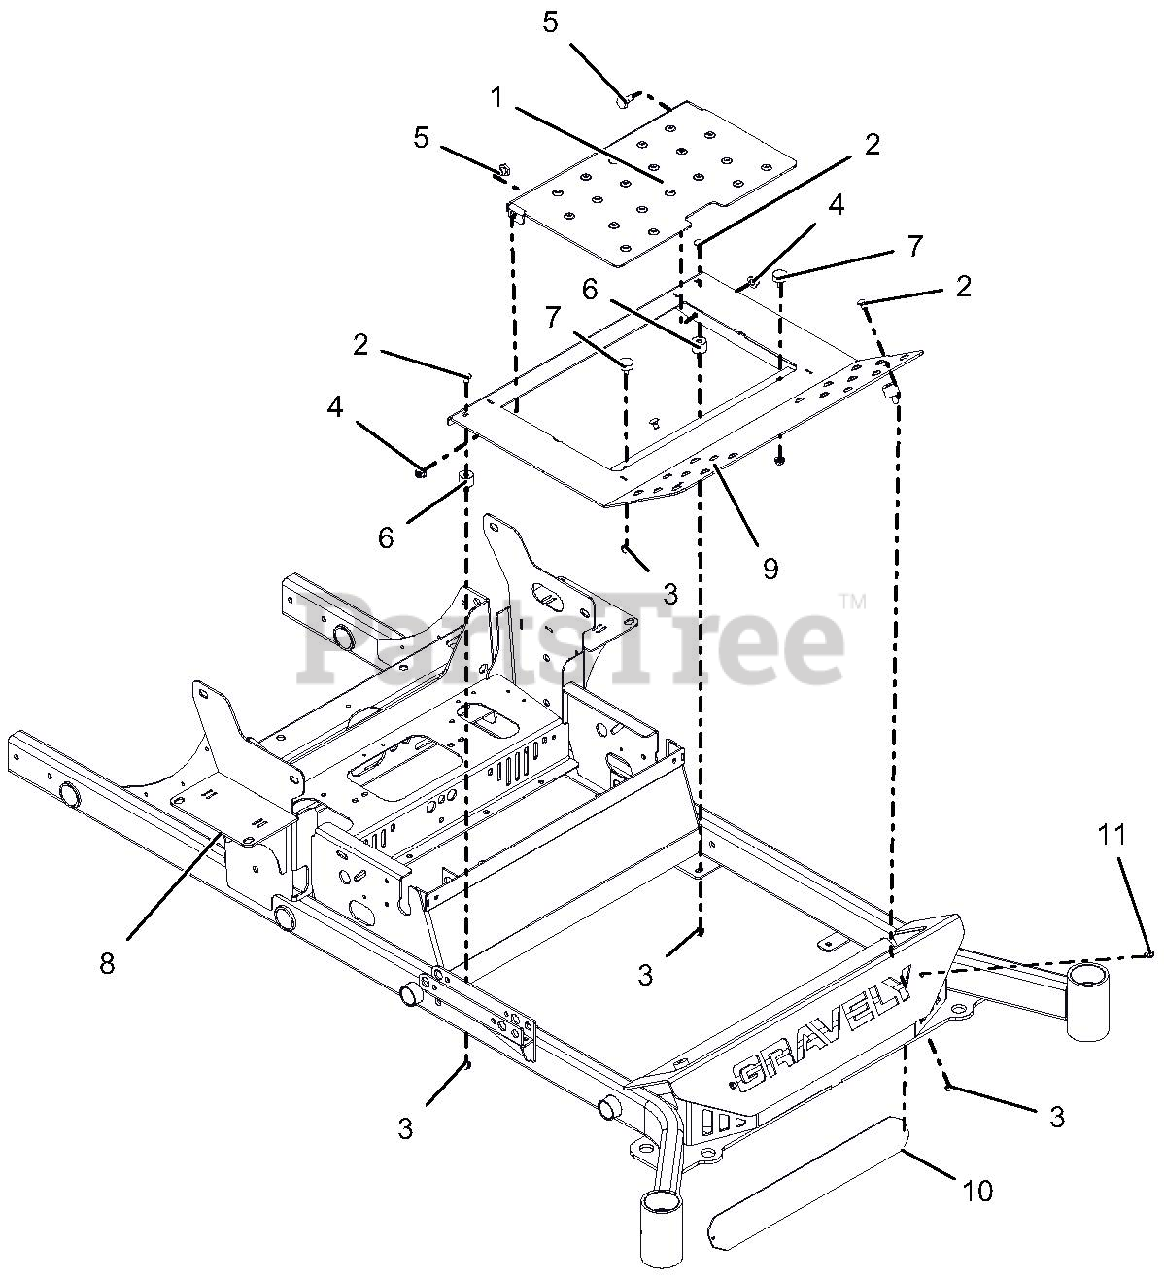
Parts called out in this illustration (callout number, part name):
1	PANEL, INSPECTION
2	@BLT-RDHDSQNK .31-18X.50 G5YZ
3	@NUT-SPNLK-FLG .312-18 YWZC
4	@NUT-LK-NYL-FLG .38-16 YWZC
5	BLT,SHLDR EP .38-16X.30 HEX YZ
6	BUMPER,STUD MNTD W/FEMALE INSR
7	BUMPER, RUBBER
8	52-60" PT400 FRAME W/DECALS
9	FOOTPLATE WLDMT W/SAFETY DECAL
10	BUMPER LOGO BACKING PLATE -BLK
11	SCR-TAP .25-20X.50 HWH TR YWZ
